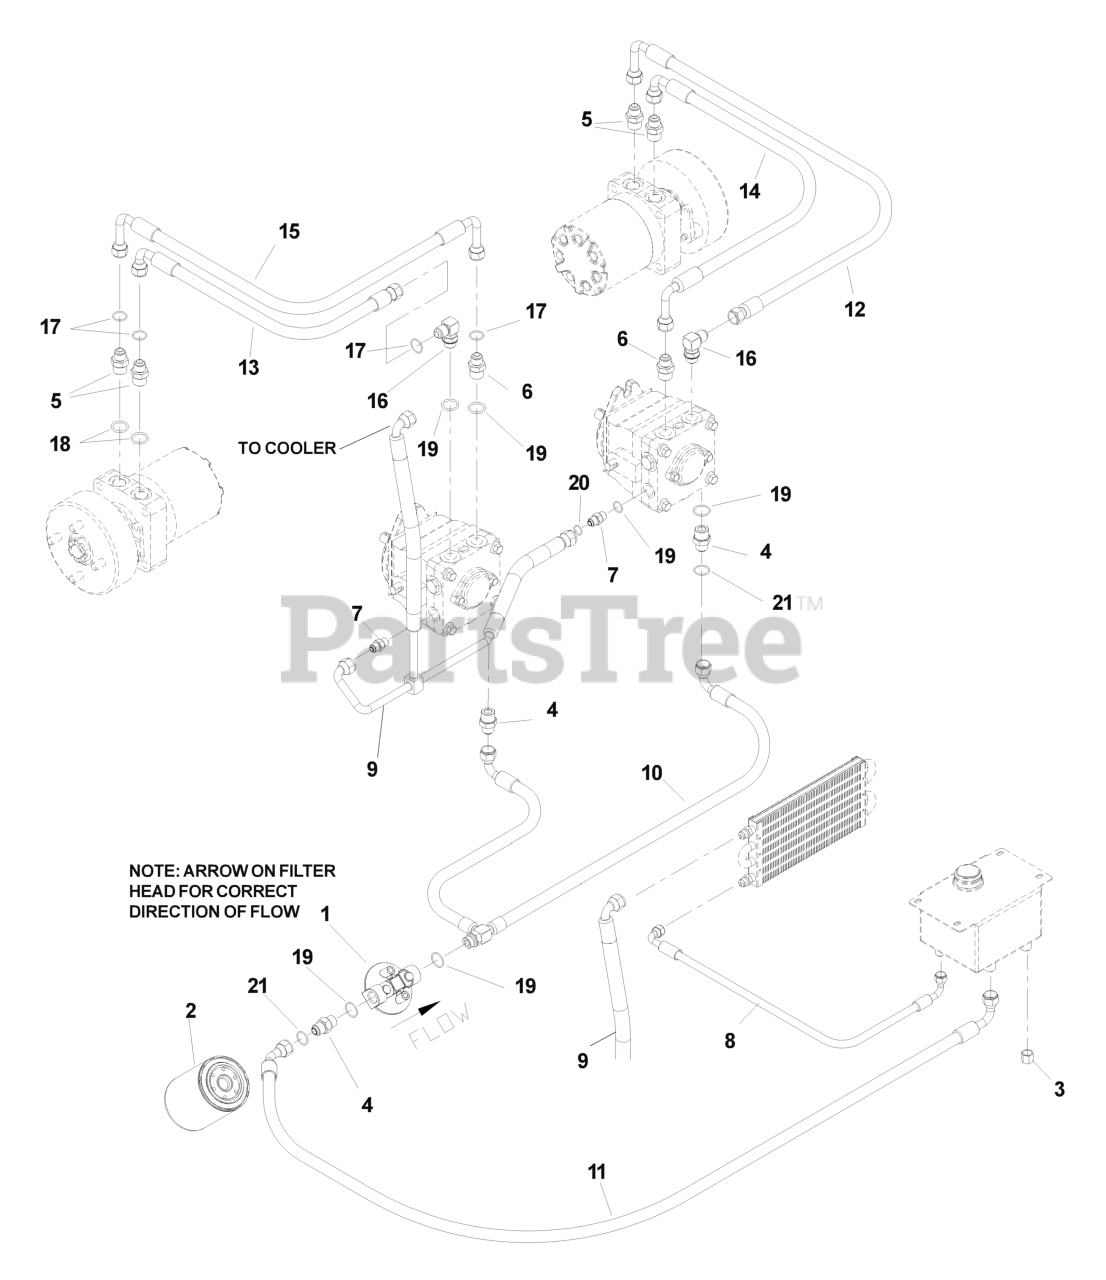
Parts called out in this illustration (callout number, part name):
1	FILTER HEAD
2	HYDRAULIC OIL FILTER
3	NUT 9/16-18 JIC CAP
4	FITTING, STRAIGHT F6400-8-8-0
